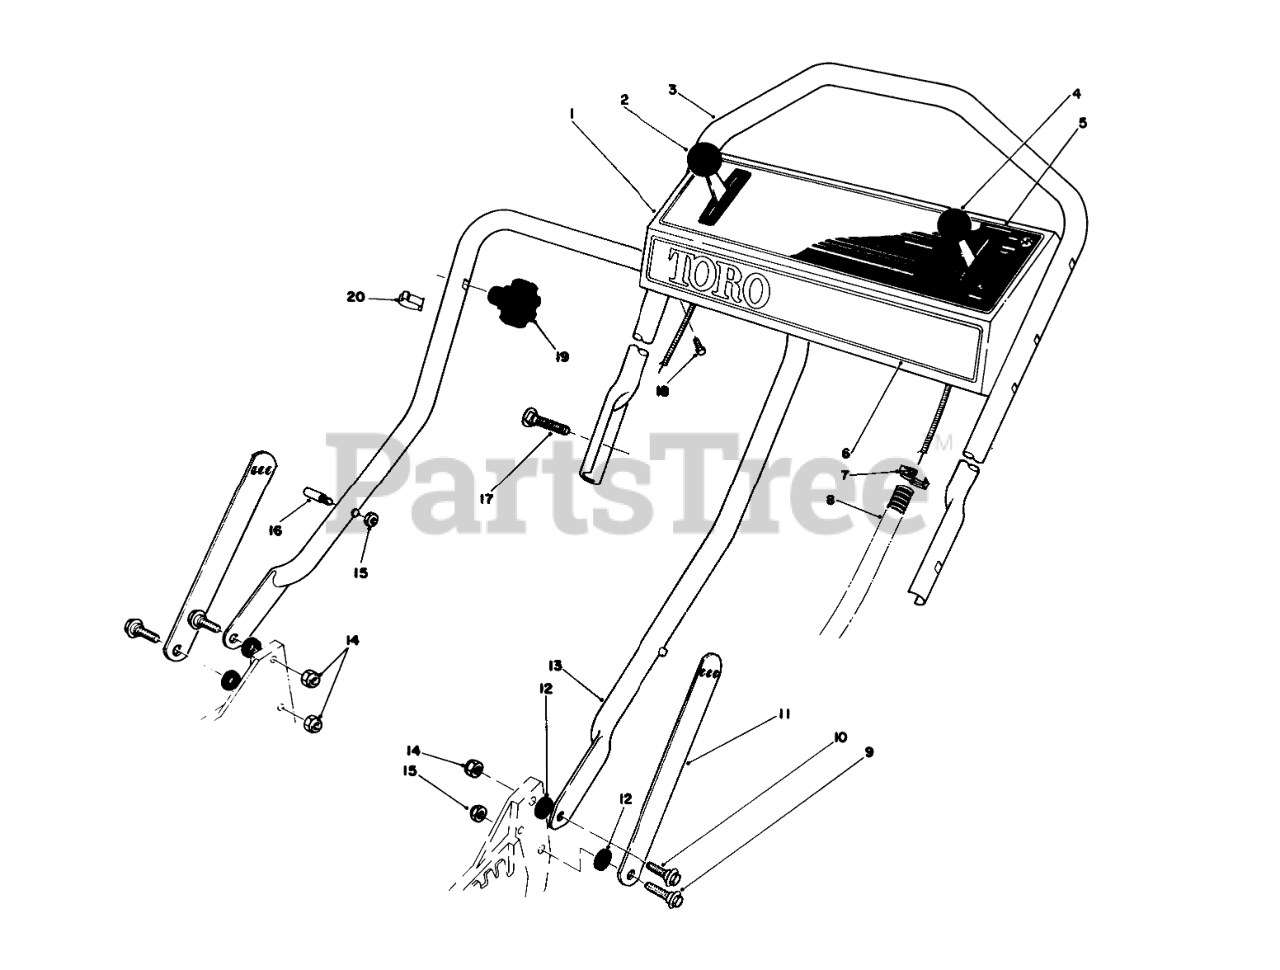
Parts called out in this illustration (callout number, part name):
1	Panel-Control (Incl. Ref. #5)
2	GROUND SPEED CONTROL
3	Handle-Upper
4	THROTTLE CONT-SERVICE
5	PANEL INST. DECAL
6	Decal-Toro
7	FITTING-RING
8	CONTROL CABLE COVER
9	SCREW-SHOULDER
10	SCREW-SHOULDER
11	Handle Latch
12	SPACER
13	LOWER HANDLE ASM
14	NUT-LOCK, NI
15	NUT-LOCK, NI
16	HANDLE PIN
17	5/16-18 X 2 HNDLE SCREW
18	SCREW-HWHTF
20	BOWDEN CLIP
